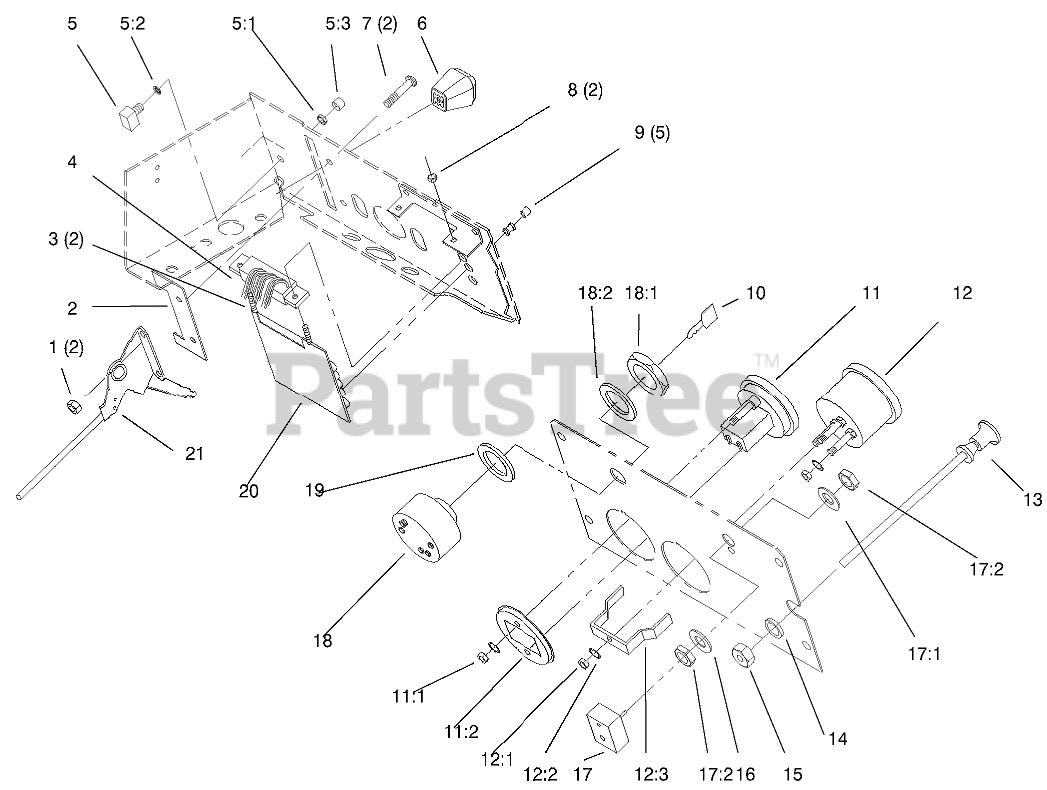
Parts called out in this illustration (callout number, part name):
1	Nut
2	Washer
3	Screw
4	P.C.-BOARD HARNESS
5	SWITCH-PUSH BUTTON
7	SCRW-PHC
8	NUT-HEX
9	ASSY LENS & BUSHING
10	KEY-IGNITION
11	VOLTMETER
12	Hourmeter
13	CONTROL CHOKE
14	WASHER-FLAT
15	NUT-HEX PALNUT
16	WASHER
17	SWITCH-LIGHTS
18	KEY SWITCH ASM
19	WASHER
20	Board-Pc
21	CONTROL-THROTTLE
